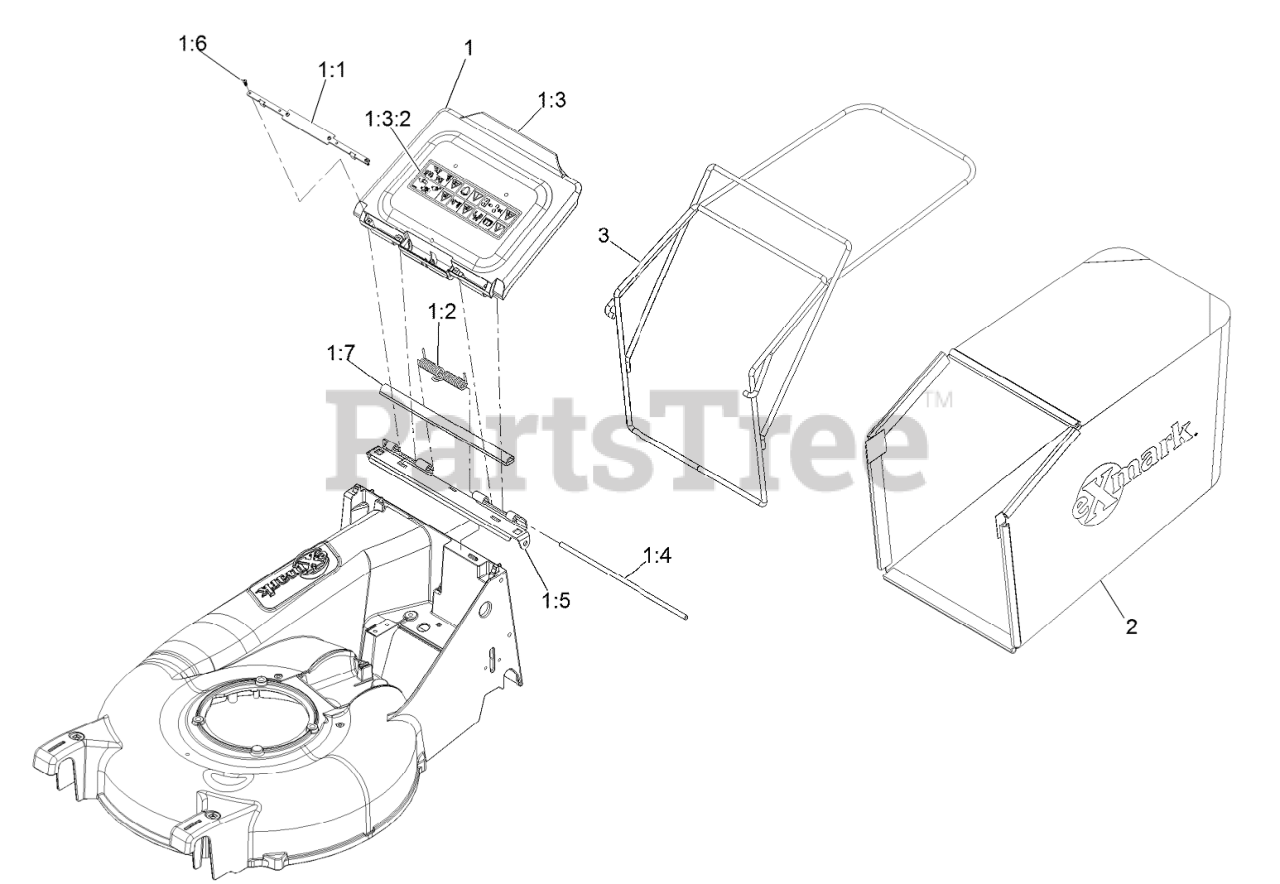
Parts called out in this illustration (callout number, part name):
1	DOOR ASM
1:1	PLATE, DOOR COVER
1:2	SPRING-PLASTIC DOOR
1:3	ASM-DOOR & DECAL
1:3:2	DECAL-WARNING
1:4	PIN-DOOR PIVOT
1:5	BRACKET-DOOR PIVOT
1:6	SCR,TAP,6-19X7/16,PHPH, S
1:7	SEAL-EPDM FOAM BULB
2	BAG-21 GRASS
3	WLD-BAG FRAME
